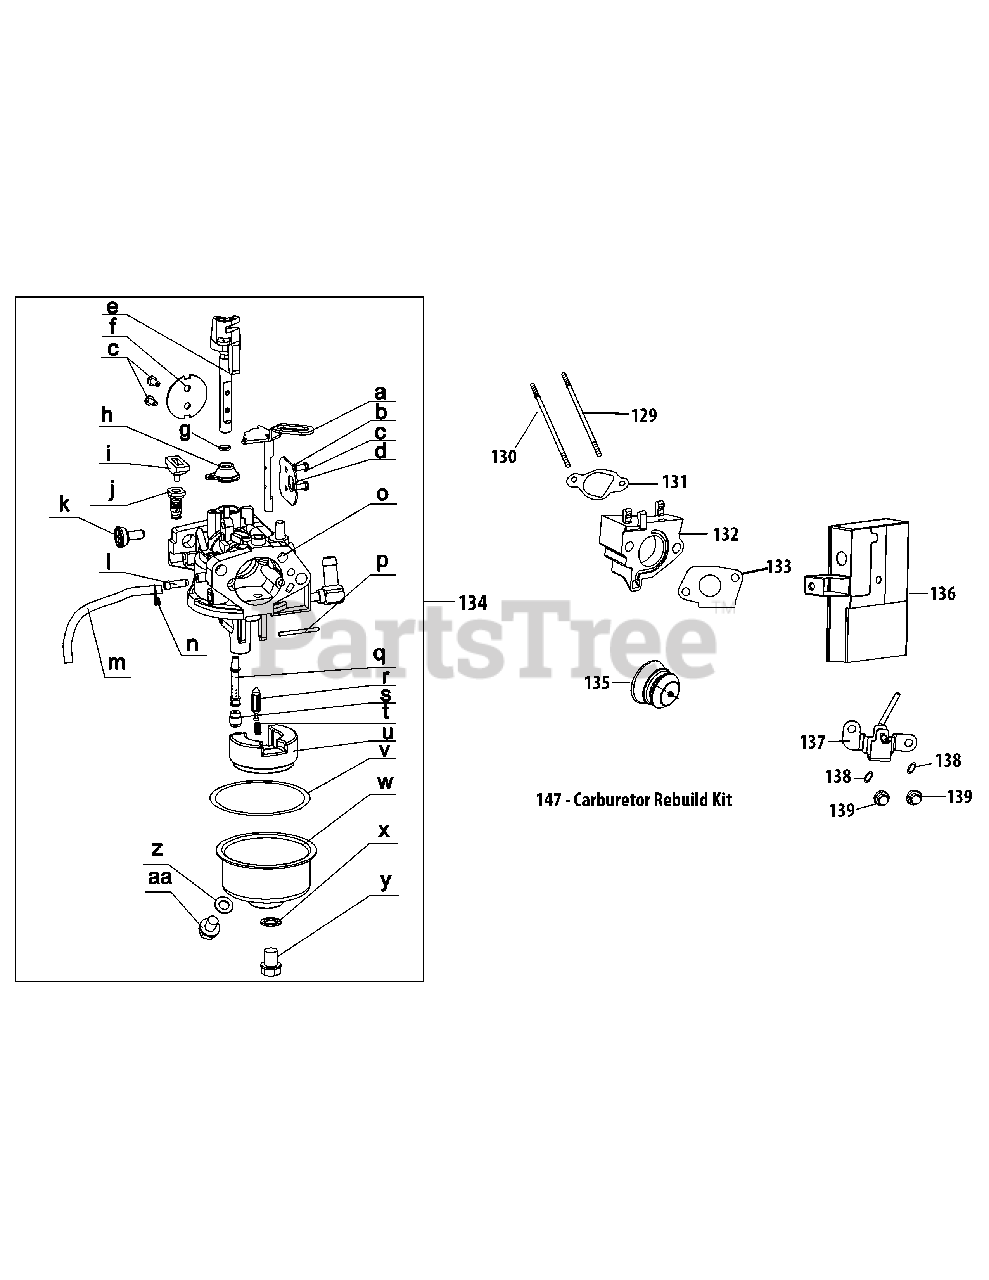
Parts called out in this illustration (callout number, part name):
129	Stud M6-8×100
130	Stud M6-8×118
131	Carburetor Intake Gasket
132	Carburetor Insulator
133	Carburetor Gasket
134	Carburetor Assembly
135	Primer Assembly
135	Primer Bulb
136	Heater Box
137	Choke Assembly
138	Lock Washer
147	Carburetor Rebuild Kit
